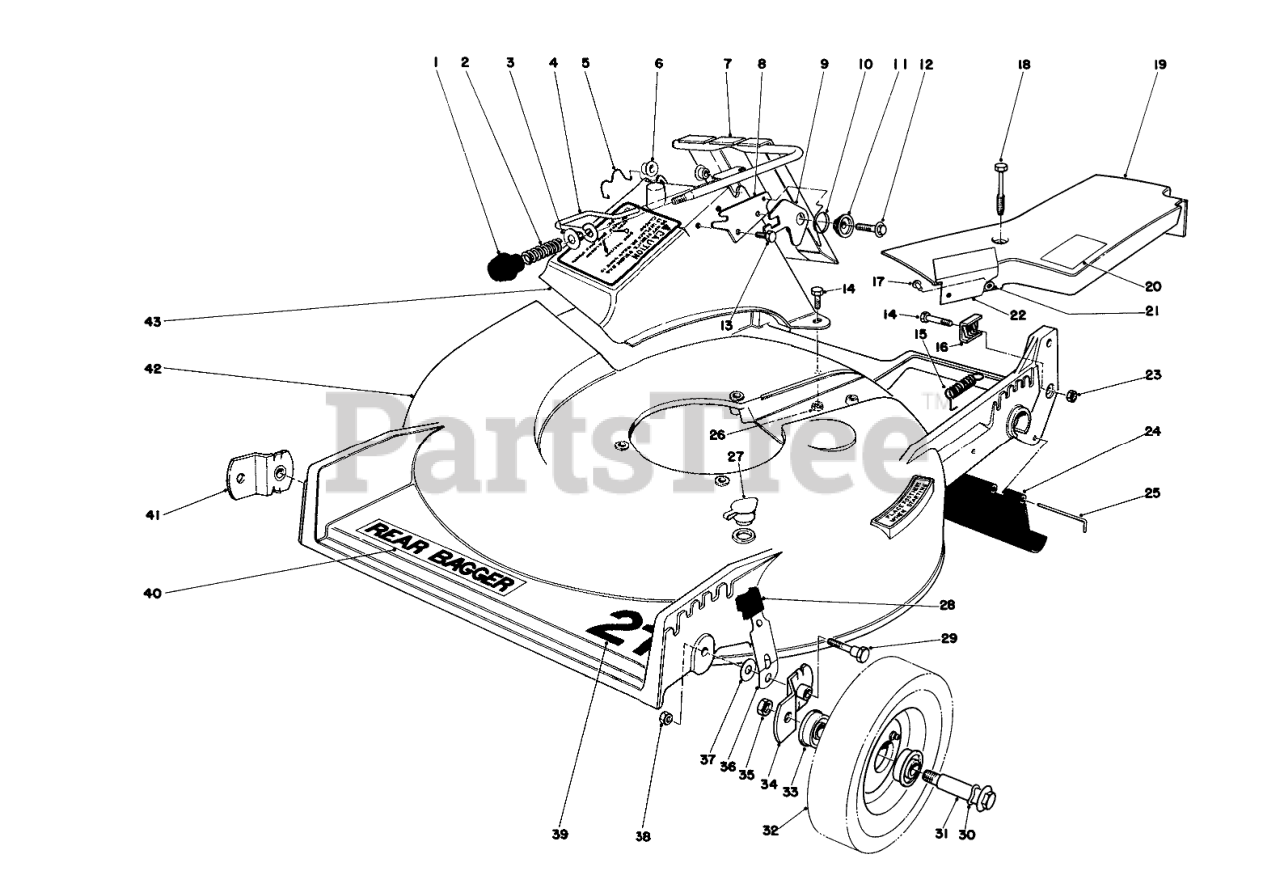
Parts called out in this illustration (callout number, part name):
2	COMPRESSION SPRING
3	WASHER
4	DOOR LATCH
5	DOOR RETAINER
6	BUSHING-NYLON
7	DOOR & HANDLE WA
8	DOOR LATCH PLATE
9	Latch Safety
10	Spring-Torsion
11	Latch Spacer
12	Screw
13	SCREW-HWH
14	SCREW-HH
15	IDLER SPRING
16	CLAMP-CABLE
17	RIVET-HEAD, FLAT
18	SCREW-HHFTF
19	Belt Cover (Incl. Ref. #17 & 21-22)
20	Sticker Grease
21	WASHER-FLAT
22	HEAT SHIELD
23	NUT-JAM
24	SHIELD - TRAILING
25	Rod Shield
26	NUT-LOCK, NI
27	Plug Washout
28	KNOB-ARM
29	PIVOT SCREW
30	SPRING WASHER
32	Wheel & Tire Assembly (Incl. Ref. #33)
33	BEARING-BALL
34	PIVOT ARM ASM A
35	Nut
36	SPRING ARM ASM (R&S)
37	WASHER-PIVOT
38	Nut
39	Decal 21"
40	DECK DECAL
41	PIVOT ARM ASM B
42	Housing
43	DISCHARGE CHUTE B
